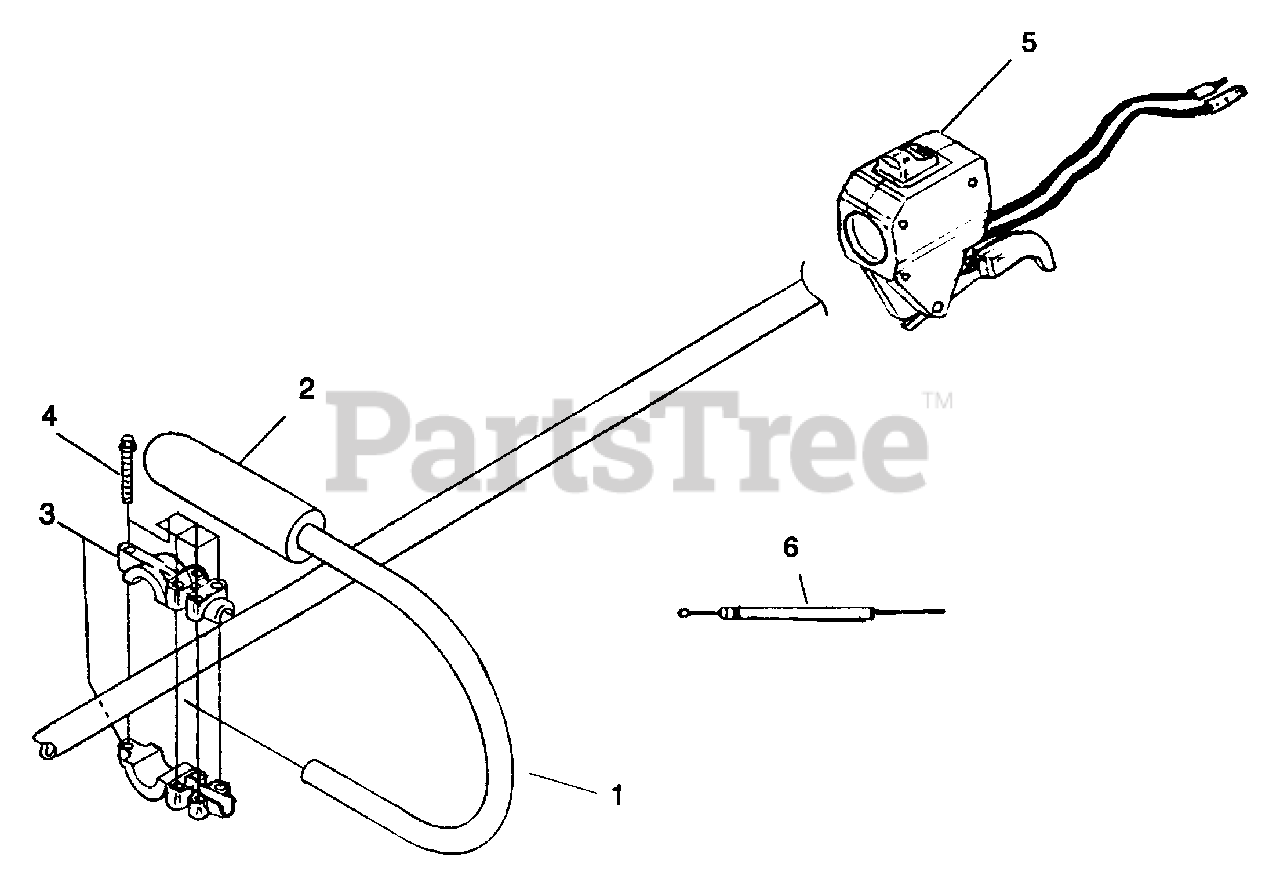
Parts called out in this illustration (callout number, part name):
1	J-HANDLE ASSY
2	GRIP
3	BRACKET ASSY
4	SCREWS
5	THROTTLE ASSY
6	THROTTLE CABLE
